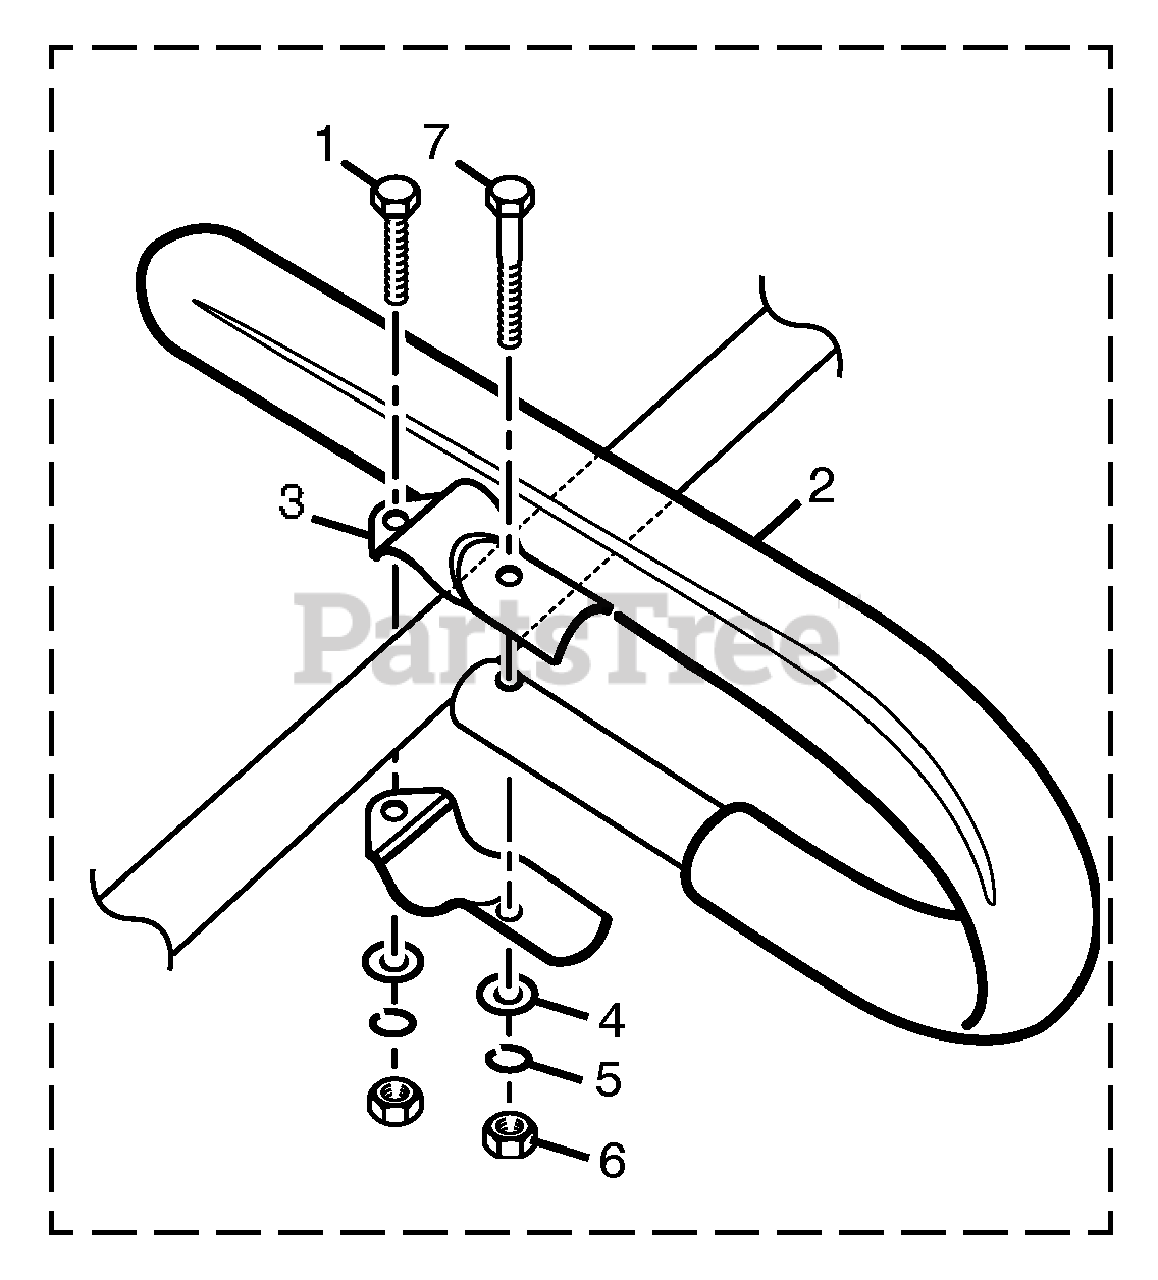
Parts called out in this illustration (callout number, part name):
2	J HANDLE & GRIP
3	HANDLE BAR CLAMP
4	WASHER
5	LOCK WASHER
6	HEX NUT
7	HEX HEAD BOLT
